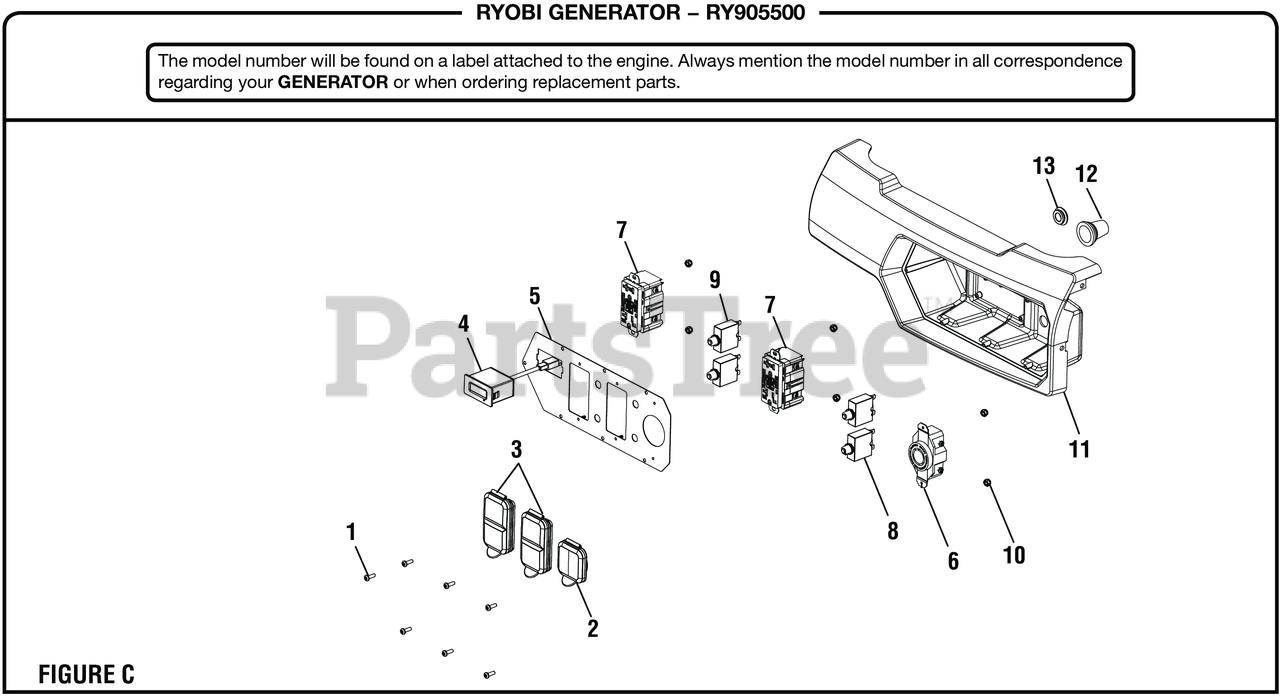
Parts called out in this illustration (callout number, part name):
1	Screw (#8-18 x 1/2 in., T20 Torx Pan Hd.)
2	240 Volt ReceptacleRain Cover
3	120 Volt Receptacle Rain Cover
4	Digital Display
5	Front Panel
6	Twist Lock Recepticle (120/240 Volt, 30 Amp, L14-30)
7	Duplex Receptacle (120 Volt)
8	Circuit Breaker (25 Amp)
9	Circuit Breaker (20 Amp, 125 Volt)
10	Lock Nut (M4)
11	Control Box (Back Panel)
12	Wiring Rubber Boot
